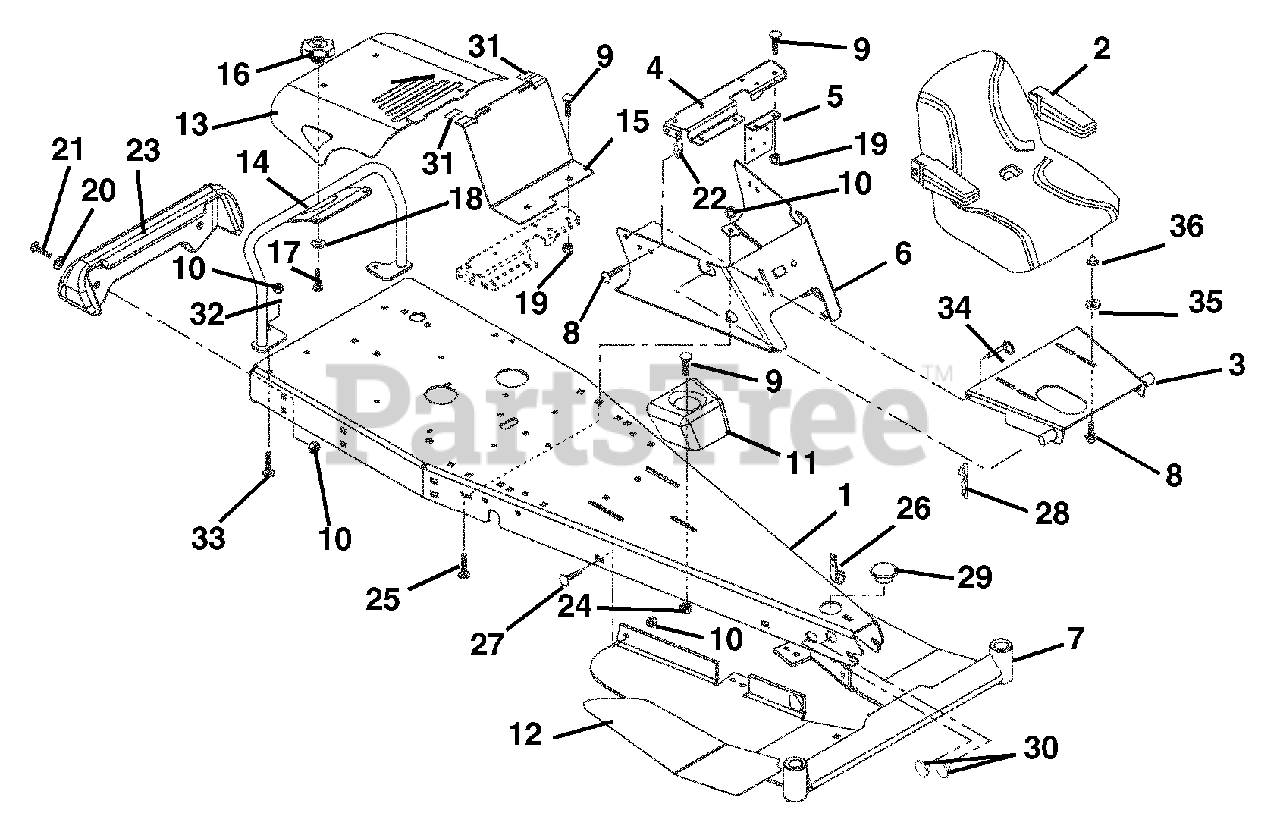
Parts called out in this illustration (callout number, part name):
1	FRAME,RER/SPORT-ZOOM
2	SEAT, TS2500 MICHIGAN W/ARM.
3	WLDM'T, SEAT PLATE
4	REINFORCEMENT, SEAT SUPPORT
5	PANEL-SOLENOID MOUNTING
6	SEAT SUPPORT
7	WLDMT-FOOTREST RER/MINI-Z-
8	BLT-SERHFWH .31-18 X 1 YWZC
9	BLT-RDHDSQNK .31-18X.75 G5BZ
10	NUT-LK-TOP-FLG .38-16 BLKZC
11	CUP HOLDER RER
12	GRIP, RER FOOTREST (LH)
12	GRIP, RER FOOTREST (RH)
13	ENGINE-HOOD ARIENS
14	WLDM'T TUBE
15	BRACKET-HOOD SUPPORT
16	KNOB-CLAMPING, .312-18 NYLOC
17	@BLT-RHDSSQNK .31-18X.75 G5YZ
18	NUT-PUSH .312
19	NUT-LK-TOP-FLG .31-18 BLKZC
20	@WSHR-FL-STL.438X1.00X.083 YWZ
21	@BLT-HEX .38-16X1.75 GR5 YWZC
22	NUT-RTNR .25-20X.56
23	WEIGHT, SPORT-Z
24	@NUT-SPNLK-FLG .312-18 YWZC
25	BLT-RDHDSQNK .38-16X.75 G5BZ
26	J-CLAMP
27	BLT-RDHDSQNK .38-16X1.00 G5BZ
28	PIN-HAIR-EXT .12X.31X2.37 YWZC
29	HOLE PLUG, 1.38
30	HOLE PLUG 1.00"
31	TAPE-FOAM .12X1.00 VINYL
32	RETAINER, .38 PUSH-ON
33	@BLT-RDHDSHSQNK.38-16X1.0 G5YZ
34	PIN-DET W/RING .25X1.00
35	SPACER, .344X1.00X.410
36	NUT-PUSH .312
